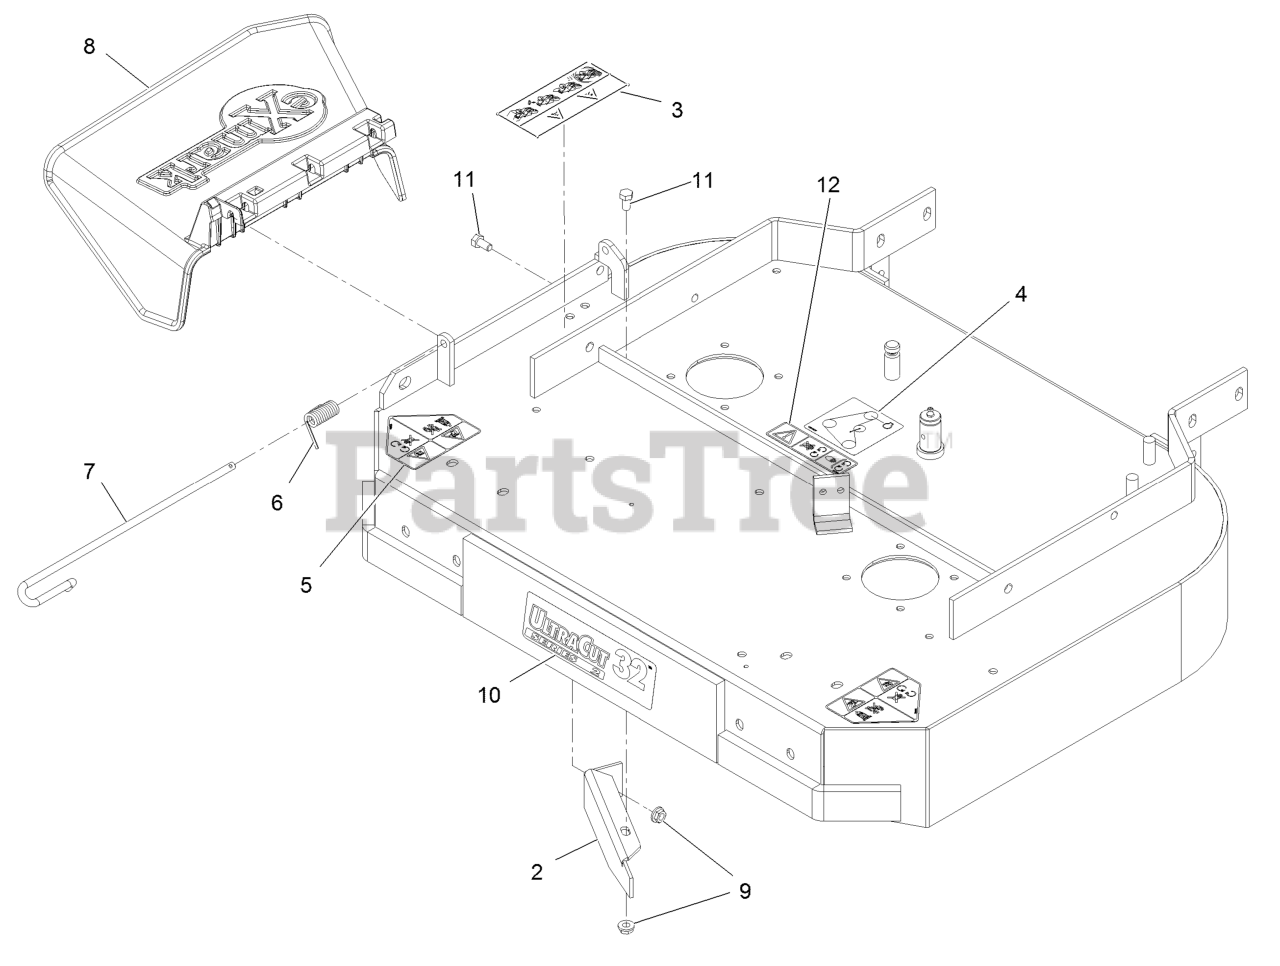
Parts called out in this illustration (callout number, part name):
2	BAFFLE-DOGLEG
3	DECAL-WARNING, BAGGER
4	DECAL-BELT ROUTING 32-36
5	DECAL-DANGER
6	SPRING, TORSION
7	PIN-CHUTE
8	CHUTE DEFLECTOR XRK M056
10	DECAL-ULTRACUT 32 SERIES
11	SCREW-HH
12	DECAL-COVER, MISSING
